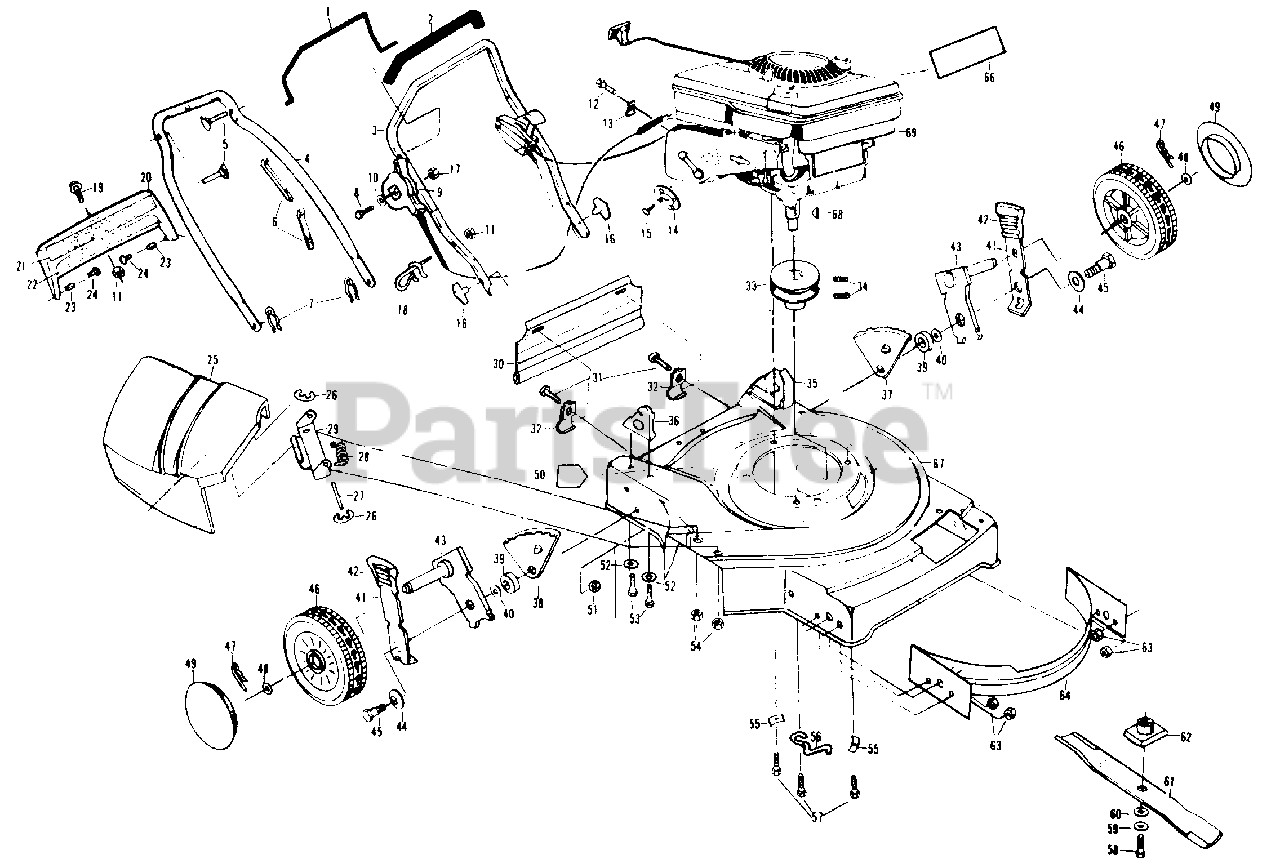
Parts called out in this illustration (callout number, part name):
1	Control Bar (AYP part number)
2	Handle Grip (AYP part number)
3	Upper Handle
4	Lower Handle (AYP part number)
5	Handle Bolt
6	Wire Tie (AYP part number)
7	Hairpin Cotter (AYP part number)
8	Machine Screw (AYP part number)
9	Throttle Control
10	Flat Washer (AYP part number)
11	Locknut (AYP part number)
12	Thread Rolling Screw (AYP part number)
16	Handle Knob (AYP part number)
17	Locknut (AYP part number)
18	Rope Guide (AYP part number)
19	Hex Washer Head Machine Screw (AYP part number)
20	Trim Plate
21	Trim Plate Decal 5.0 HP
22	Trim Plate Decal (AYP part number)
23	Nylon Bushing (AYP part number)
24	Tapping Screw (AYP part number)
25	Discharge Guard (AYP part number)
26	E-Ring (AYP part number)
27	Hinge Rod (AYP part number)
28	Torsion Spring (AYP part number)
29	Housing Bracket (AYP part number)
30	Rear Skirt (AYP part number)
31	Hex Washer Head Tapping Screw (AYP part number)
32	Skirt Bracket (AYP part number)
33	Engine Pulley (AYP part number)
34	Set Screw (AYP part number)
35	Handle Bracket Assembly (Left)
36	Handle Bracket Assembly (Right)
37	Wheel Adjusting Bracket (Left)
38	Wheel Adjusting Bracket (Right)
39	Spacer (AYP part number)
40	Flat Washer (AYP part number)
41	Selector Spring (AYP part number)
42	Selector Knob (AYP part number)
43	Axle Arm Assembly (AYP part number)
44	Belleville Washer (AYP part number)
45	Shoulder Bolt (AYP part number)
46	Wheel and Tire Assembly (AYP part number)
47	Retainer Clip (AYP part number)
48	Flat Washer (AYP part number)
50	Danger Decal (AYP part number)
51	Locknut (AYP part number)
52	Flat Washer (AYP part number)
53	Thread Cutting Screw (AYP part number)
54	Locknut (AYP part number)
55	Engine Washer (AYP part number)
56	Belt Snubber (AYP part number)
57	Hex Head Thread Rolling Screw (AYP part number)
58	Hex Head Screw
59	Helical Lockwasher (AYP part number)
60	Hardened Washer (AYP part number)
61	22" Blade
62	Blade Adapter (AYP part number)
63	Locknut (AYP part number)
64	Front Baffle (AYP part number)
66	"Poulan" Decal (AYP part number)
67	Lawn Mower Housing (Inc. Ref. #50)
68	Hi-Pro Key #HP-505 (AYP part number)
